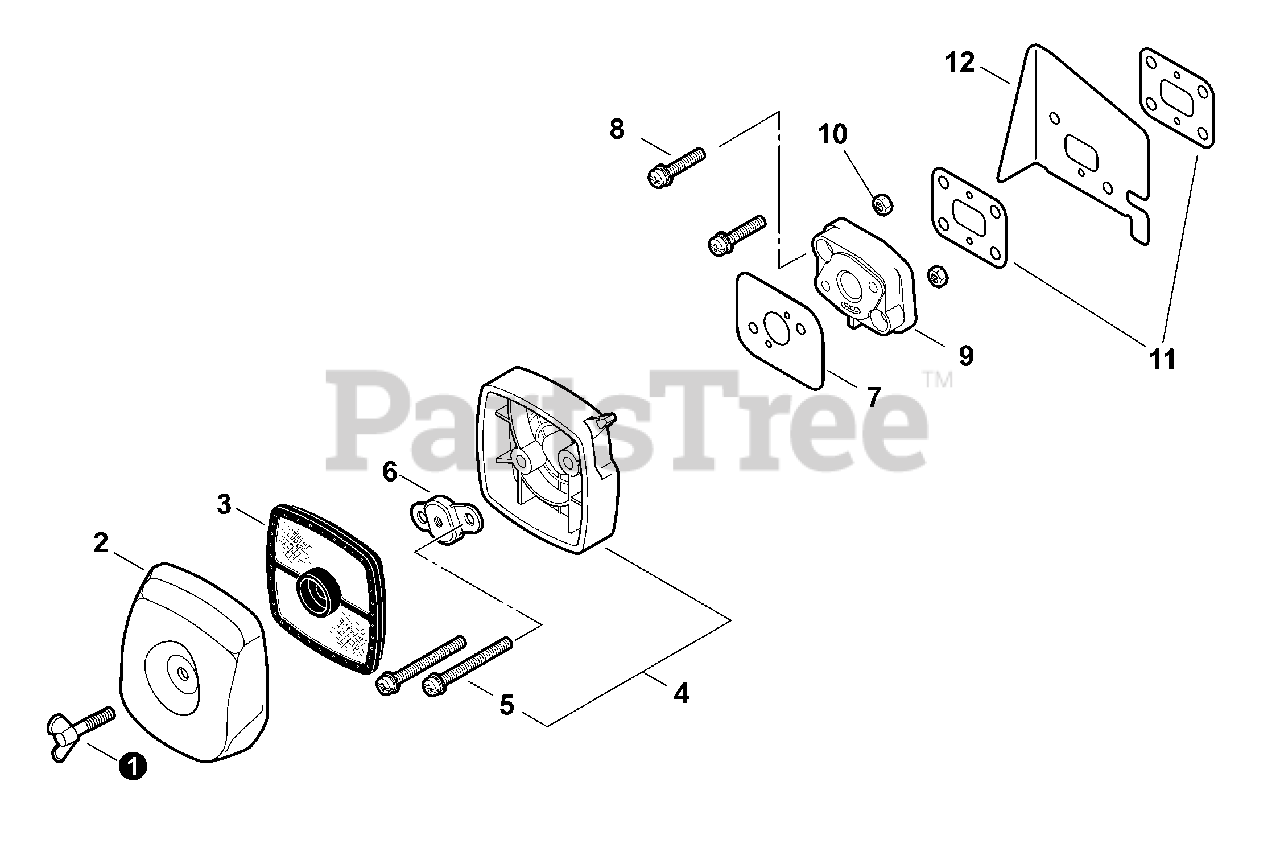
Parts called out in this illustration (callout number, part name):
1	BOLT, WING 5×20
2	COVER, AIR FILTER - BLACK
3	FILTER, AIR - DOUBLE LAYER
4	CASE ASSY, AIR FILTER
5	SCREW 5×65
6	PLATE, PREVENT
7	GASKET, INTAKE
8	SCREW 5×22
9	INSULATOR, INTAKE
10	NUT M5
11	GASKET, INTAKE
12	HEAT SHIELD, INTAKE
